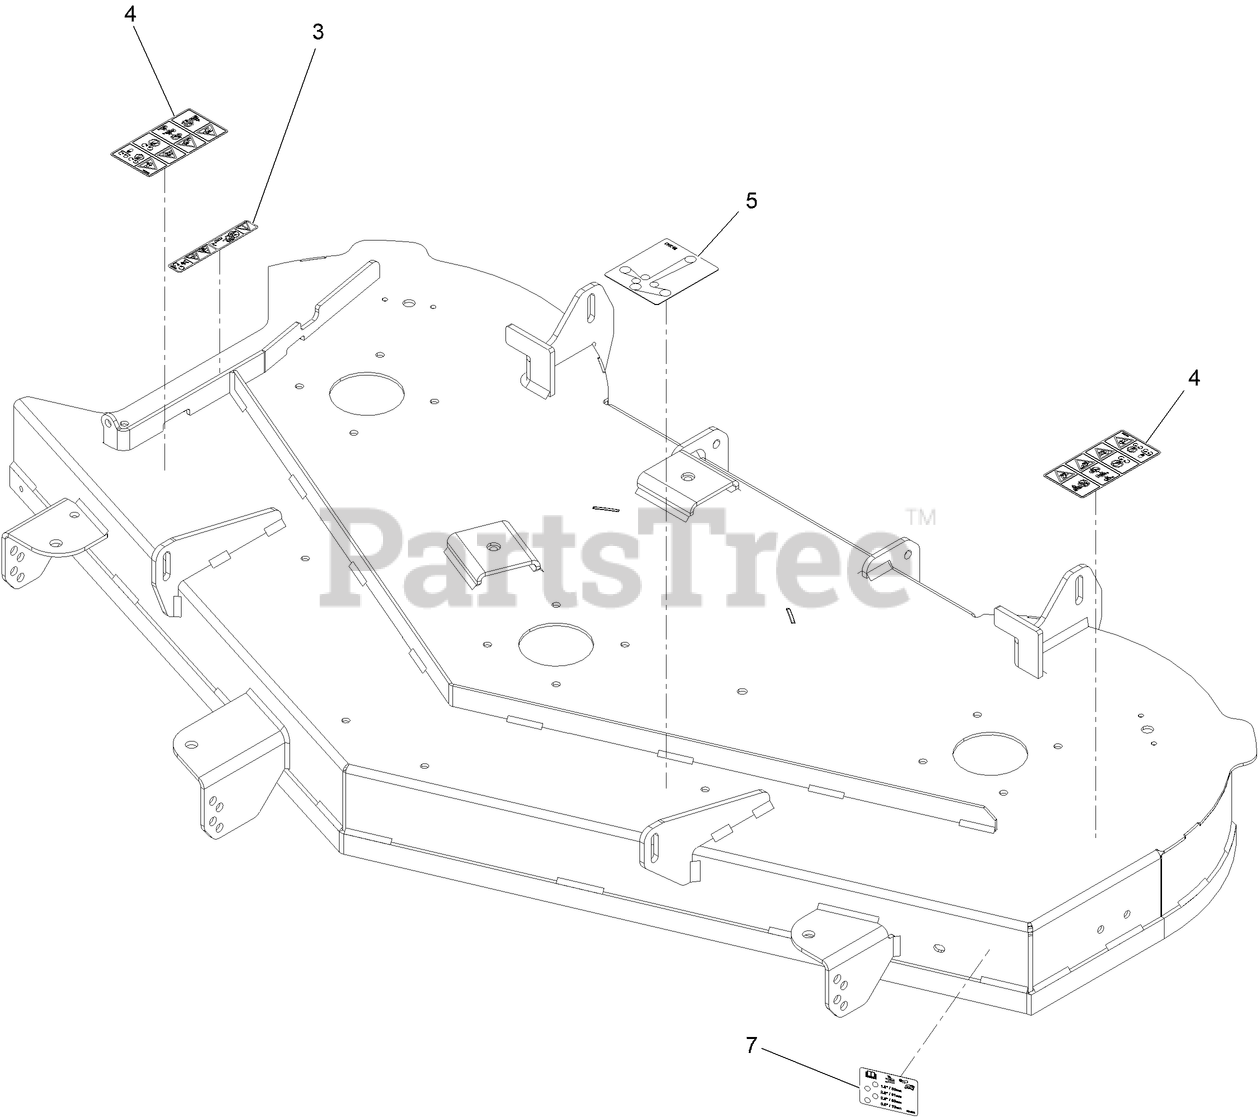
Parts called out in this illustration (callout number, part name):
3	DECAL-DANGER
4	DECAL-DANGER, DECK
5	DECAL-ROUTING, BELT
7	DECAL-SCALP, ANTI
